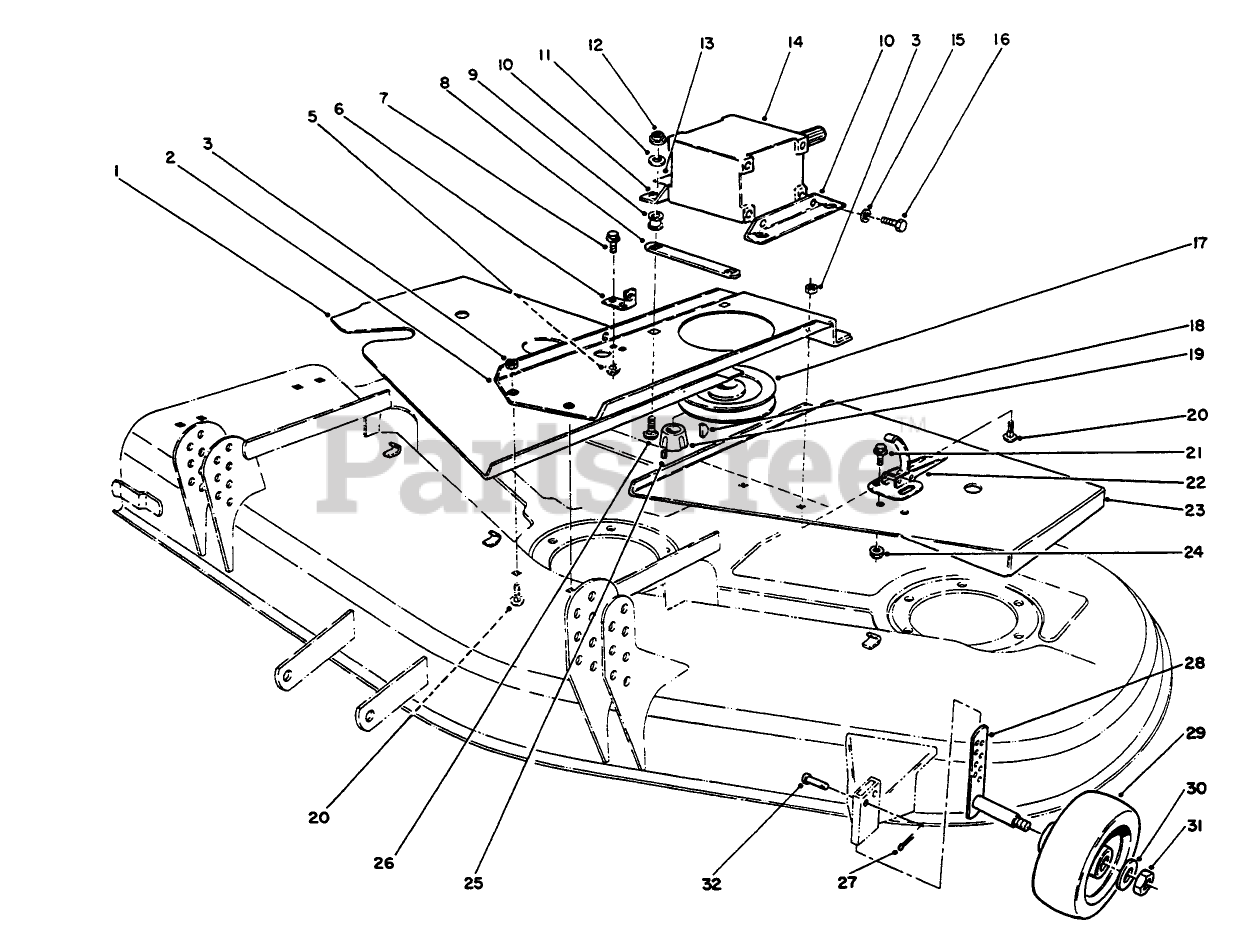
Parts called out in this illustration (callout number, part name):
1	Cover RH
2	Base-Gear Box
3	NUT-HHF, WHIZ
5	NUT-HF
6	Bracket-Extension
7	SCREW-HH
8	Cover-Gear Box
9	MOUNT
10	Bracket-Gearbox
11	WASHER
12	NUT-LOCK, SIDE
13	DECAL-OIL
14	Gearbox
15	WASHER-LOCK
16	SCREW-HH
17	PULLEY
18	KEY-WOODRUFF
19	Bushing-Taper Lock (Incl. Ref. #25)
20	SCREW-CARR
21	SCREW-HWH
22	CLAMP-SLOTTED
23	Cover LH
24	NUT-LOCK, FLANGE
25	SCREW-SET, HSH
26	SCREW-CARR
27	PIN-HAIR
28	GAGE-WHEEL
29	WHEEL-GAGE
30	WASHER-FLAT
31	NUT-LOCK, NI
32	PIN-CLEVIS
